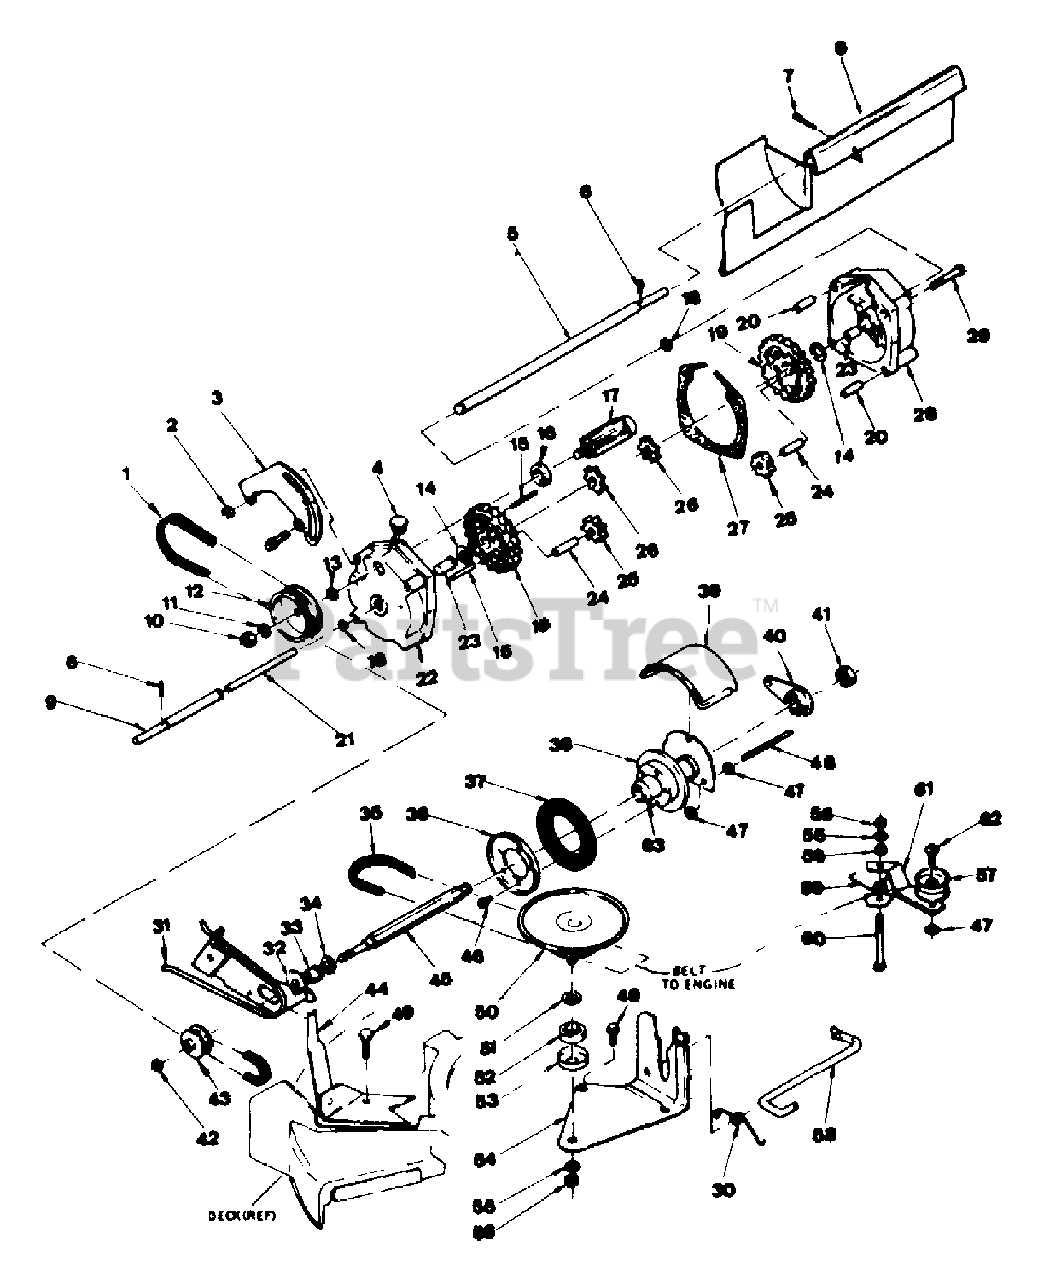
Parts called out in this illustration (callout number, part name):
1	Belt
2	1/4 28 Hex Lock Nut
3	Transmission Bracket
4	Plug
5	Long Axle
6	3/16 x 1-1/8 Roll Pin
7	1/8 x 3/4 Cotter Pin
8	Guard Structure
9	Short Axle
10	NUT, 5/16-24 Hex Lock, GR C
11	Spring Washer
12	Polly "V" Pulley
13	Spring Washer
14	Thrust Washer
15	Roll Pin, 3/16 x 1 5/8
16	Ball Bearing
17	Input Gear Assembly
18	Seal
19	46 Tooth Gear
20	Roll Pin
21	Shaft
22	Inboard Housing
23	Bearing
24	Shaft
25	11 Tooth Gear
26	Differential Gear Axle
27	Gasket
28	Outboard Housing
29	1/4-28 x 3-1/4 HHCS
30	Bell Crank Spring
31	Belt Guard Assembly
32	Thrust Washer
33	Bushing
34	Thrust Washer
35	3L 250 Engine Belt
36	Tire Plate
37	RING, Driven (Rubber Disc)
38	Driven Disc Assembly
39	Cover
40	Bearing Holder Assembly
41	1/16-20 Hex Nut
42	3/8-24 Hex Lock Nut
43	Poly "V" Pulley
44	Belt Guard Assembly
45	Hex Shaft
46	SCREW, #10-24 x 1/2" Hex Washer Self-Tap (Torx)
47	1/4-28 Hex Lock Nut
48	Clutch Rod
49	5/16-18 x 5/8 SEMS
50	Drive Disc Assembly
51	3/8 SAE Washer
52	Felt Seal
53	Bearing Shield
54	Deck Bracket
55	3/8 Internal Tooth L' Washer
56	3/8-24 Hex Nut
57	Idler Pulley
58	Bell Crank
59	Idler Spring
60	3/8-24 x 3 HHCS
61	Idler
62	1/4 28 x 1-1/4 HHCS
63	Shifter Cone
